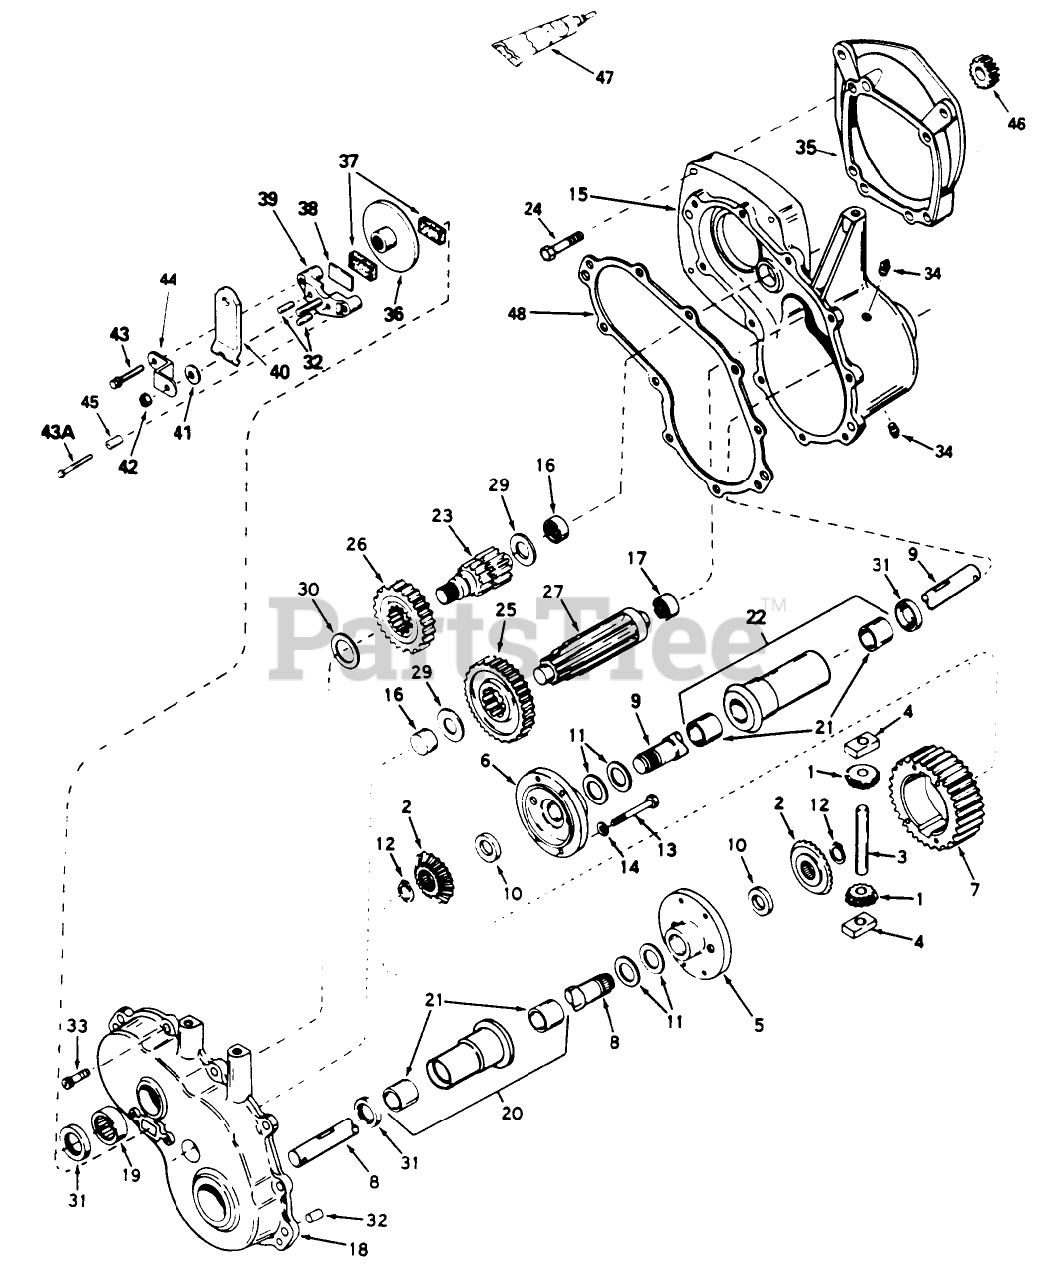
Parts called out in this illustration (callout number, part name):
1	Pinion-Bevel
2	Gear-Bevel
3	Pin-Drive
4	Biock-Drive
5	Carrier-Differential
6	Carrier-Differential
7	Gear-Ring
8	Axle-16-5/8"
9	Axle-21-57/64"
10	Washer
11	Washer
12	Ring-Snap
13	Screw-Hex Hd.
14	Lockwasher
15	Case Assembly (Incl. Ref. #16 & 17)
16	Bearing
17	Bearing-Needle
18	Cover Assembly (Incl. Ref. #16 & 19)
19	Bearing Needle
20	Housing Assembly-6-5/8" (Incl. Ref. #21)
21	Bushing
22	Housing Assembly-8-5/8" (Incl. Ref. #21)
23	Shaft-Brake
24	Screw-Hex Hd.
25	Gear-Output
26	Gear-Spur
27	Shaft-Output
29	Washer
30	Washer
31	Seal-Oil
32	Dowel Pin
33	Screw-Thread Forming
34	Plug-Pipe
35	Plate-Adapter
36	Disc-Brake
37	Pad-Brake (Pack of 2)
38	Brake Pad Plate
39	Nozzle-Carburetor
40	Lever-Brake
41	Washer
42	Locknut
43	Screw
43A	Screw-Thread Forming
44	Bracket
45	Spacer
46	Gear-Spur 22T
47	Gasket Eliminator
48	Gasket
